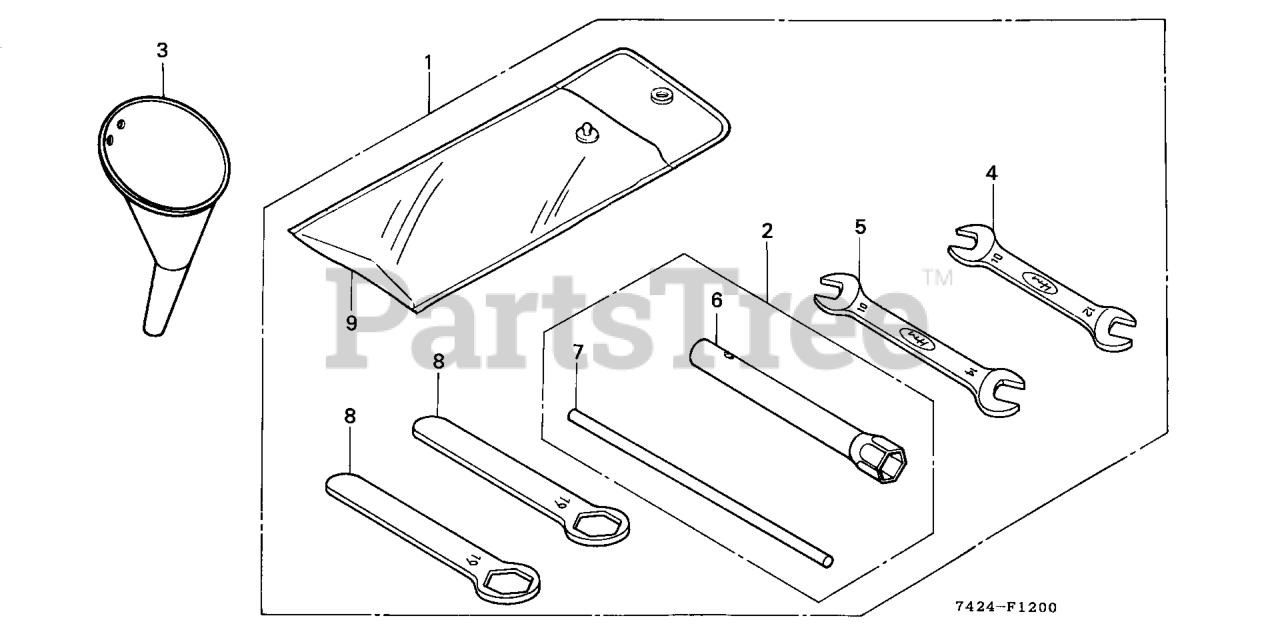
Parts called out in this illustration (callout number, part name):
3	FUNNEL, OIL
6	WRENCH, BOX (P21)
7	BAR A, HANDLE
